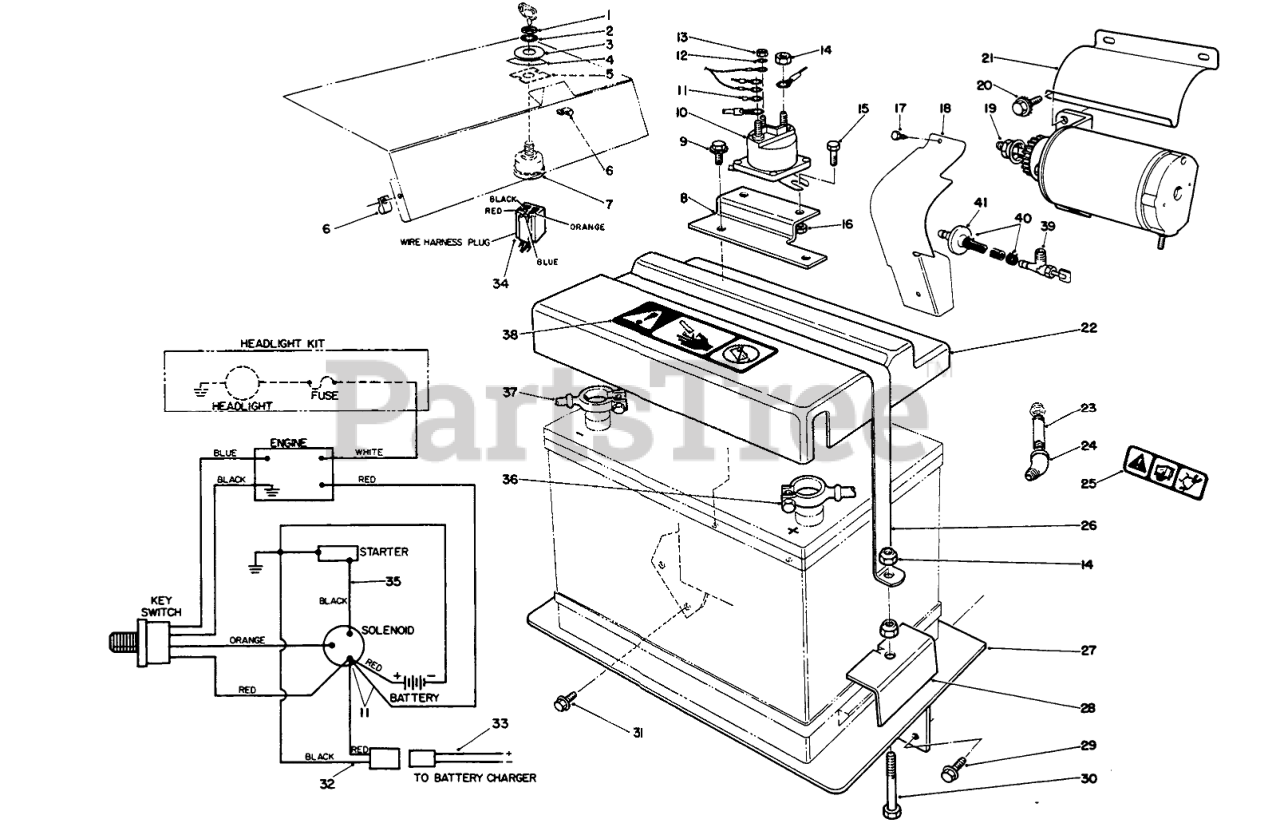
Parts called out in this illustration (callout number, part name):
1	NUT-HH
2	WASHER-TOOTH, INTERNAL
3	WASHER
4	DECAL
5	ADAPTER
6	R CLAMP
7	Switch-Starter (Incl. Ref. #1-2)
8	BRACKET
9	SCREW-HWH
10	SOLENOID
11	RING TONGUE TERMINAL
12	WASHER-LOCK, INT
13	NUT-HEX
14	NUT-LOCK, NI
15	SCREW-HH
16	NUT-LOCK, NI
17	Screw
18	Shield-Pinion
19	Starter Motor Ass-y
20	Crew
21	Shield-Dip
22	BATTERY COVER
23	NIPPLE 3/8NPTX 1.50
24	ELBOW
25	DECAL-WARNING
26	Strap Battery
27	Plate-Battery
28	BATTERY CLAMP
29	SCREW-HHF
30	SCREW-HH
31	SCREW-HHF
32	MALE WIRE ASM
33	FEMALE WIRE ASM
34	WIRE HARNESS
35	STRT MTR-SOLNOID WIRE
36	BATT-SOLENOID CABLE
37	BATT-GROUND CABLE
38	DECAL
39	Valve-Fuel Tank
41	Filter
